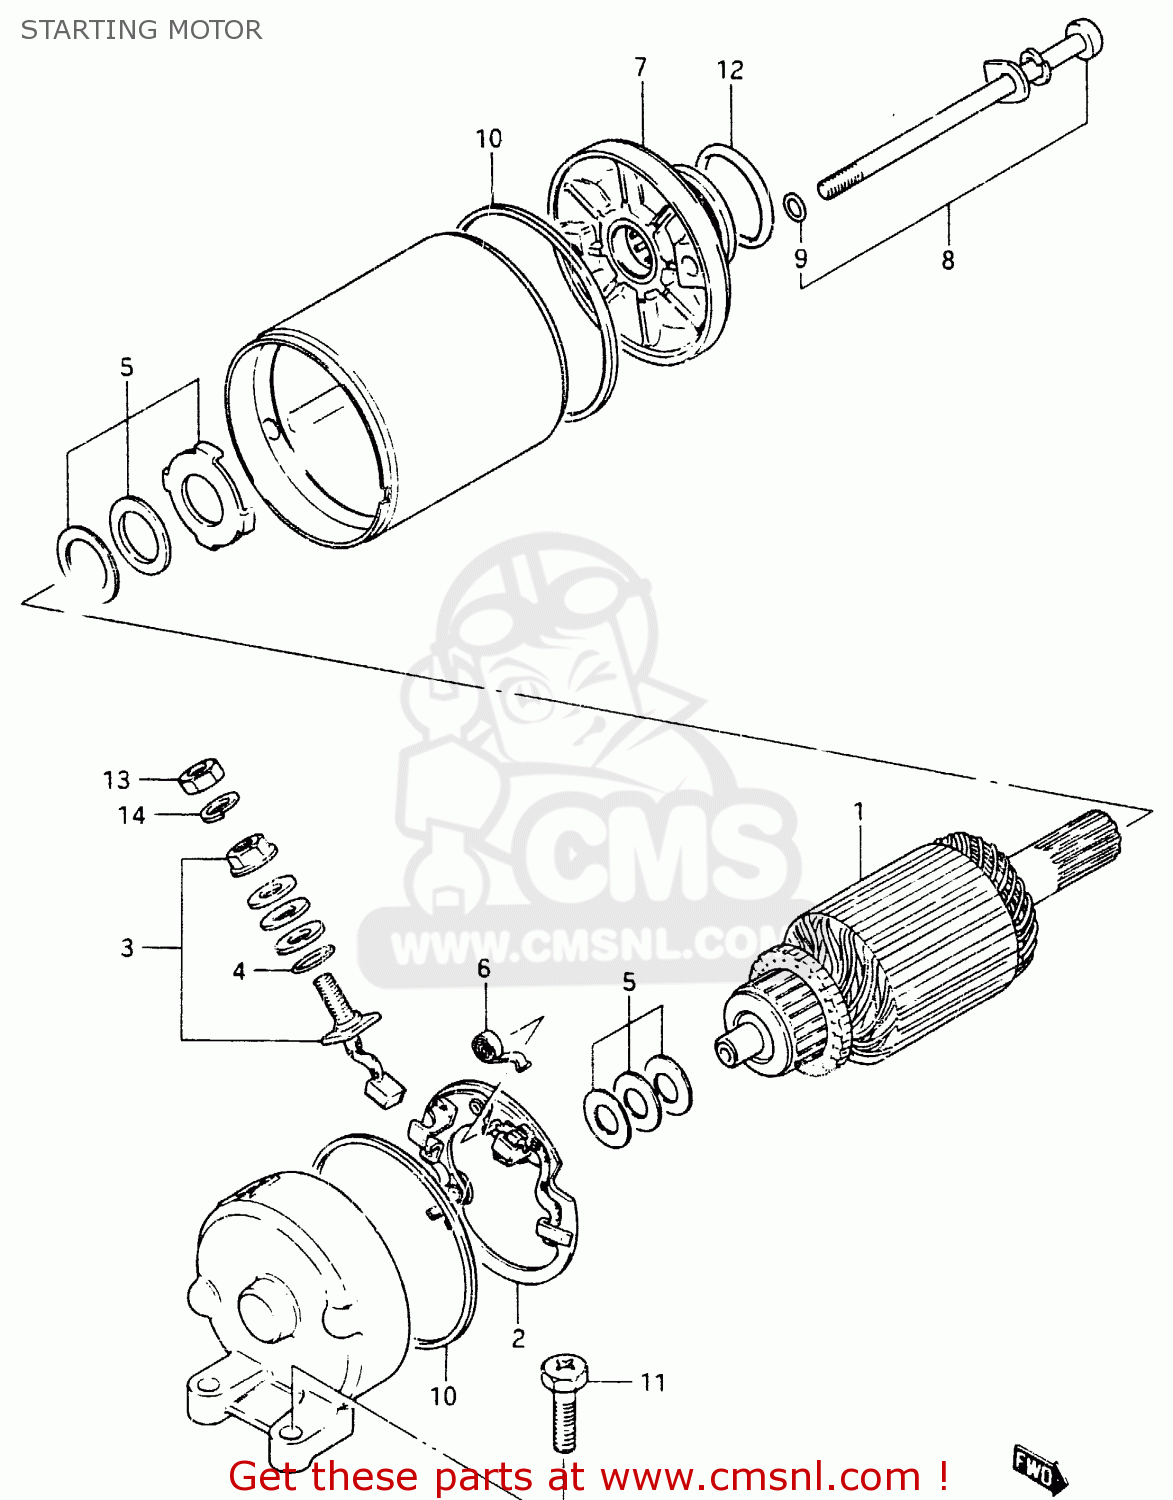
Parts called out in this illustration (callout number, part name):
1	ARMATURE
2	HOLDER SET,BRUSH(-)
3	TERMINAL SET,BRUSH,PLUS
4	O RING
5	SHIM SET,STARTING MOTOR
6	SPRING,BRUSH
7	BRACKET SET,STARTING MOTOR
8	BOLT SET,STARTING MOTOR
9	O RING
10	O RING
11	SCREW (6X25)
12	O RING(D:3,ID:24.5)
13	NUT
14	WASHER,LOCK
